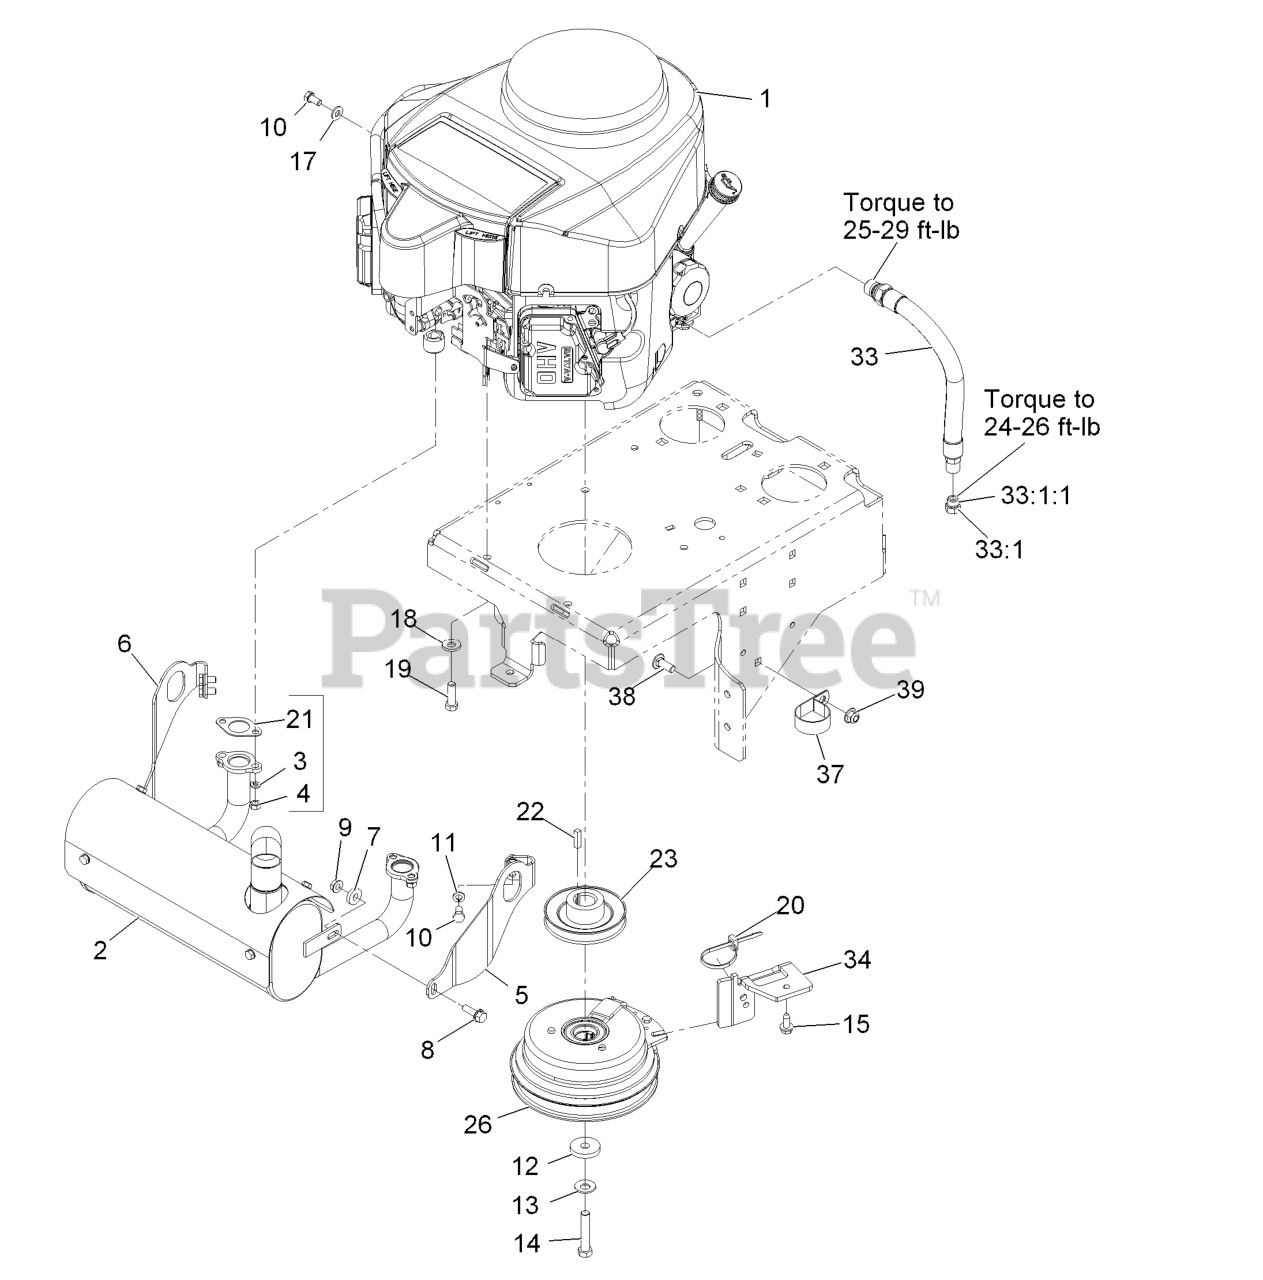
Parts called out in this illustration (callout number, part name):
3	WASHER-LOCK
5	BRACKET-MUFFLER MOUNT, LH
6	BRACKET-MUFFLER MOUNT, RH
8	SCREW-HHF
10	SCREW-HH
11	WASHER-LOCK
12	WASHER
13	WASHER-SPRING
14	SCREW-HH
15	Screw-HWH 5/16-18 X 3/4 Tf
17	WASHER-PLAIN
18	WASHER-BELLEVILLE
19	SCREW-HH
20	TIE-CABLE
21	GASKET-EXHAUST
26	CLUTCH-WARNER
33	ENGINE OIL DRAIN HOSE ASM
33:1	PLUG-HH
33:1:1	O-RING
34	BRACKET-ANCHOR, CLUTCH
37	CLAMP-R
38	SCREW-CARR
39	NUT-HF, NI
